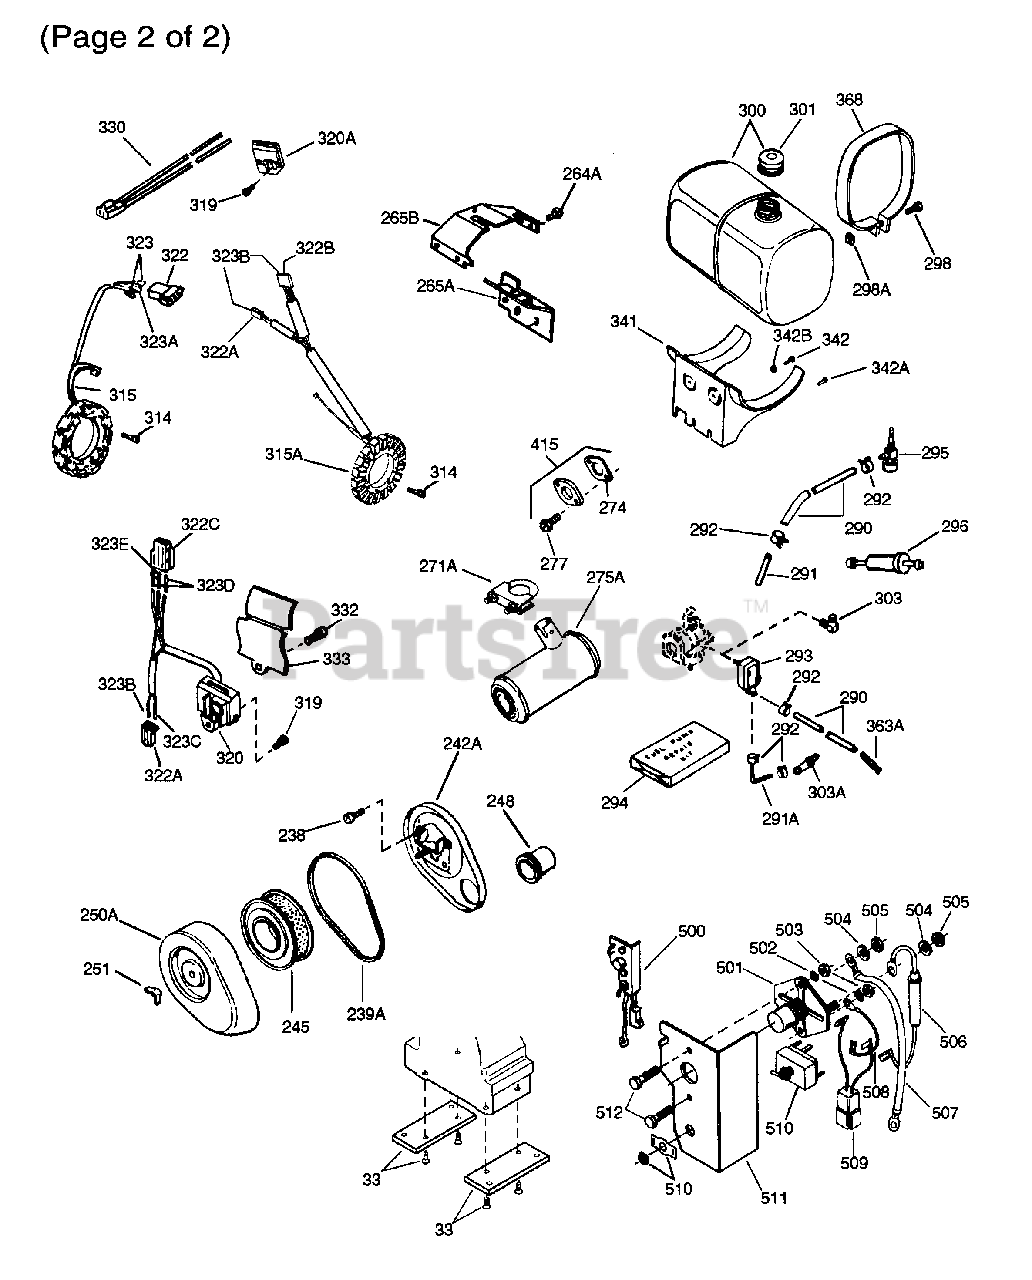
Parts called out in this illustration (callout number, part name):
16B	Governor Spring Plate
210A	Conduit Clip
211A	Screw, 10-32 x 3/8"
239A	* Air Cleaner Gasket
242A	Air Cleaner Bracket
245	Air Filter
248	Air Cleaner Tube
251	Wing Nut, 1/4-20
261A	Screw, 1/4-20 x 7/16"
274	* Exhaust Gasket
290	Fuel Line (8.62")
291	Fuel Line (8.62")
291	Fuel Line (21.00")
291A	Fuel Line (8.62")
292	Fuel Line Clamp
293	Pulse Pump
294	Pulse Pump Repair Kit (Walbro pumps o nly)
295	Fuel Shut-Off Valve
296	Fuel Filter (Incl. 292) also availabl e as Packaged Part #740003B
298	Screw, 1/4-20 x 1-1/4"
300	Fuel Tank
303	Fuel Fitting
314	Screw, 10-32 x 1-1/8"
315	Alternator Coil (20 Amp) Incl. 322B,3 23,323E
319	Screw, T-30, 1/4-20 x 1/2"
320	Regulator Incl. 322A,322C,323B,323C, 323D&323E
322B	Connector Body
323	Terminal
323E	Terminal
341	Fuel Tank Bracket
342	screw, 1/4-20 x 5/8"
342A	Screw, 5/16-18 x 5/8"
342B	Belleville Washer
355	Starter Handle
368	Fuel Tank Strap
500	Electric Starter Switch Incl. 501-51 2
